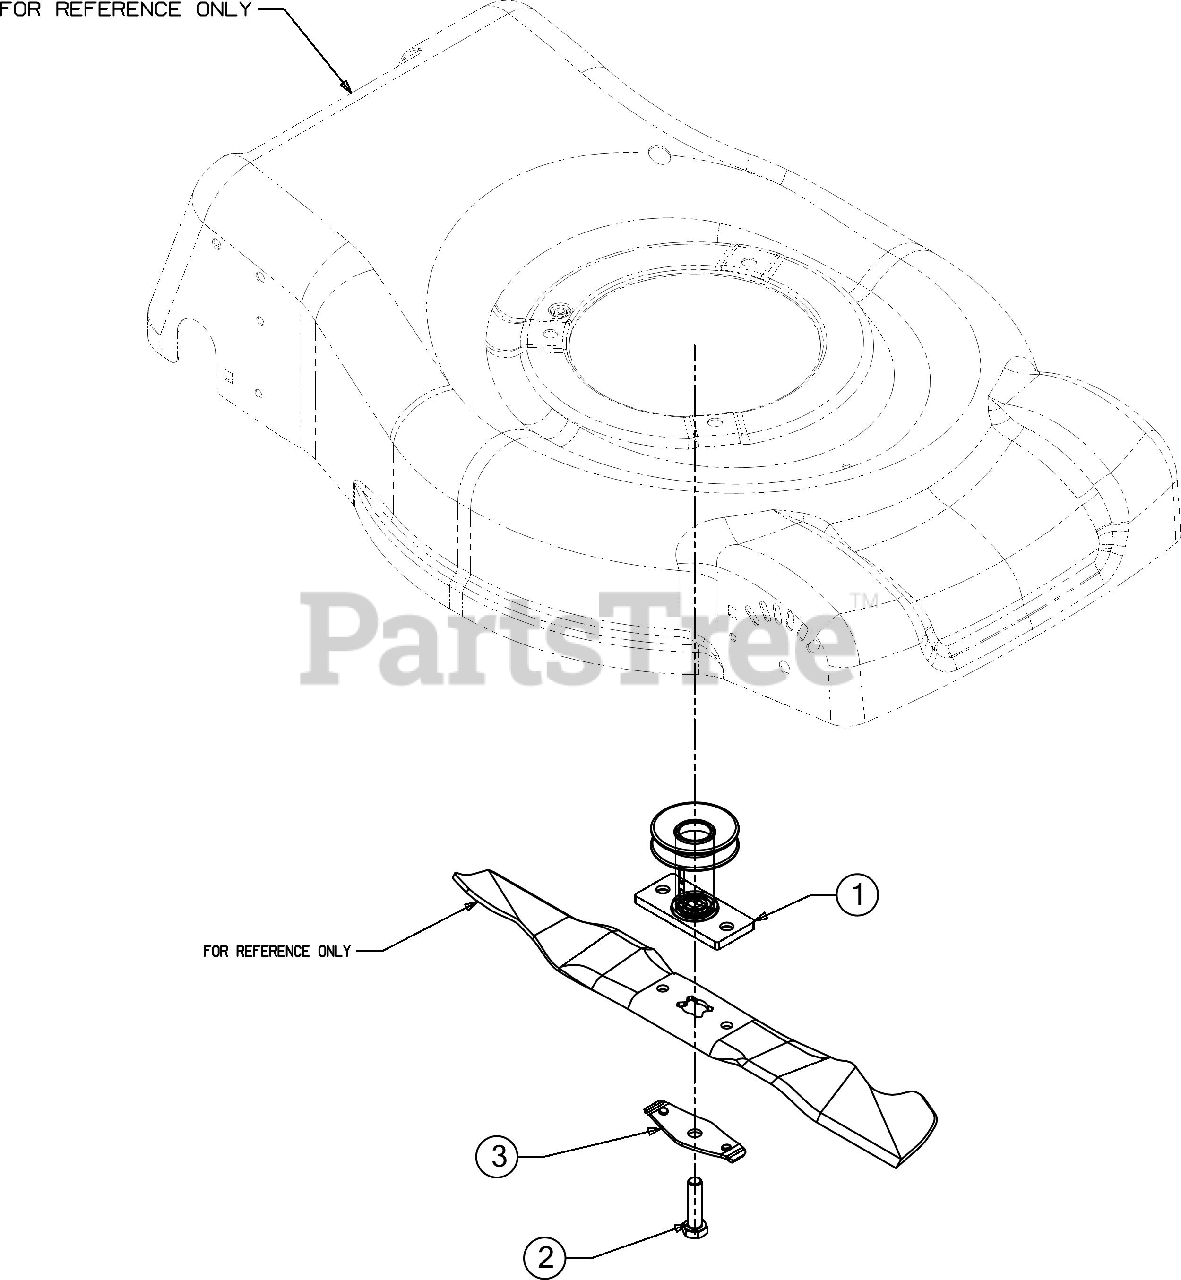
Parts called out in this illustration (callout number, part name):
1	ADAPTER ASSEMBLY(7/8 ID X .430)
2	SCREW 3/8-24 X 1.50 GR8
3	BLADE BELL SUPPORT
